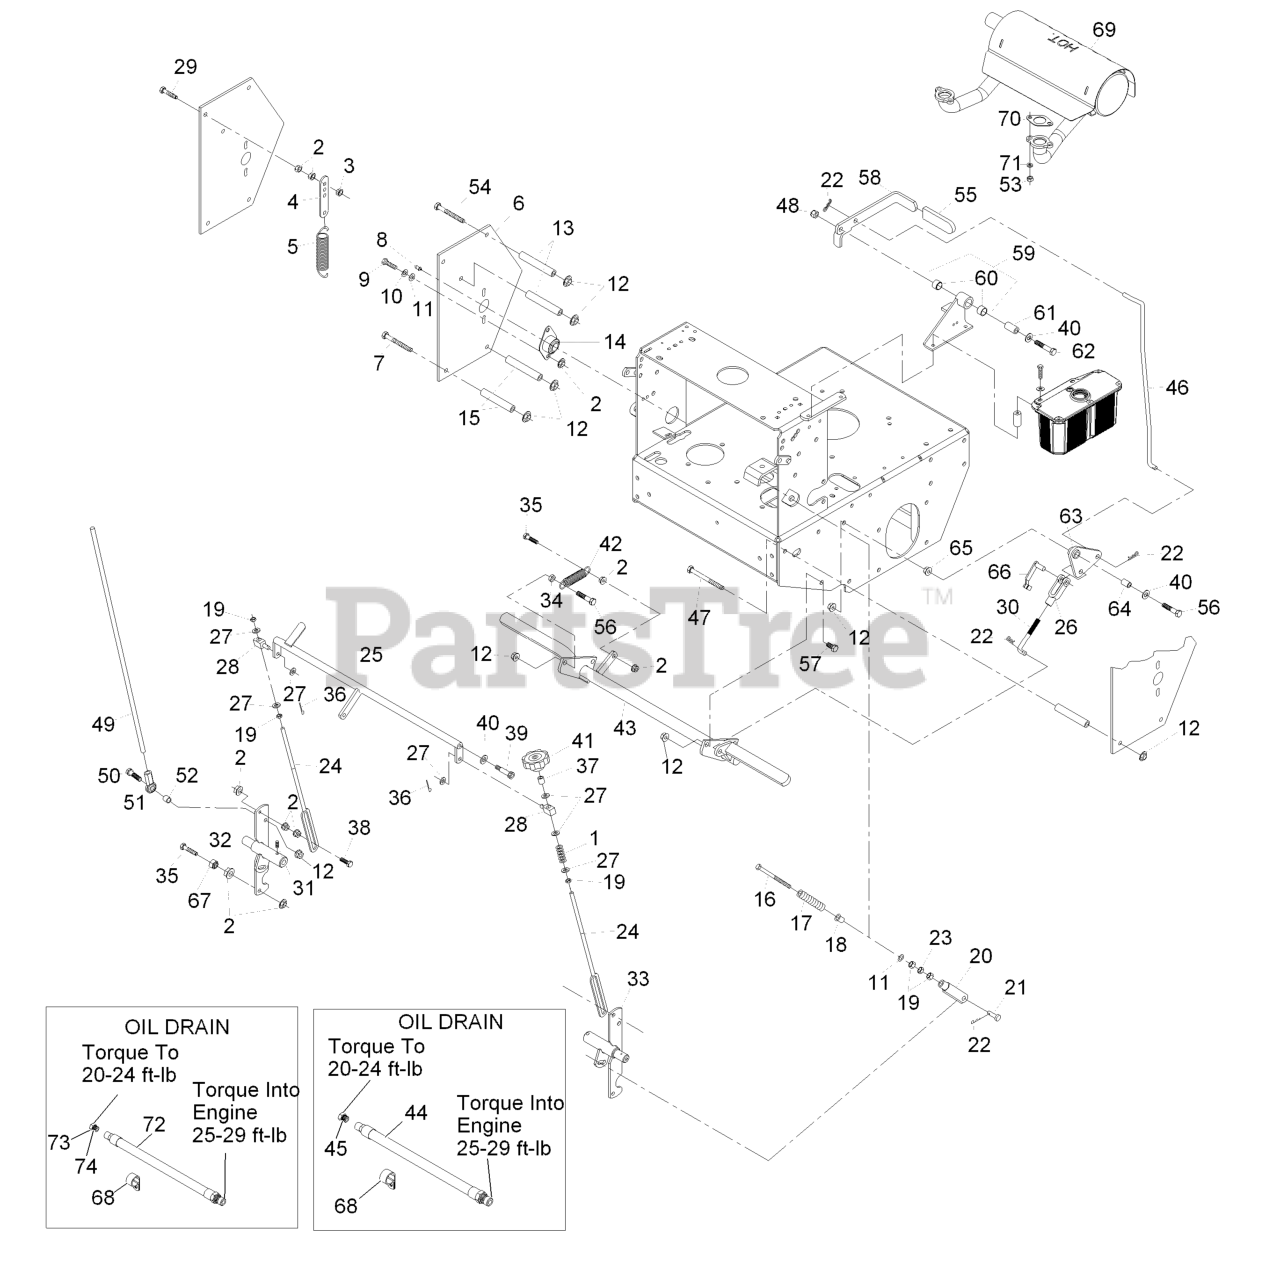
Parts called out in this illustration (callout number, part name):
1	SPRING-COMPRESSION
3	NUT-LOCK, NI
4	TAB-SPRING, EXTENSION
5	SPRING-EXTENSION
6	SHIELD-CONTROL
7	SCREW-HH
8	FITTING-GREASE
9	SCREW-HH
10	WASHER-LOCK
11	WASHER-FLAT
12	NUT-HHF, WHIZ
13	SPACER-SHIELD
14	BEARING-FLANGE, SIDE
15	SPACER-SHIELD
16	BOLT-RETURN, NEUTRAL
17	SPRING,COMPRESSION (NEUT)
18	BUSHING-FLANGED
19	NUT-HEX
20	YOKE-ADJUSTABLE
21	PIN-CLEVIS
22	PIN-COTTER
23	NUT-JAM
24	LINK-CONTROL, SPEED
25	CRANK-CONTROL, SPEED
26	YOKE-LINKAGE, BRAKE
27	WASHER-PLAIN
29	BOLT-TAP, HH
30	LINKAGE-LOWER
31	SCREW-SET
32	SHAFT-CONTROL, LH
33	SHAFT-CONTROL, RH
34	NUT-JAM
35	SCREW-HH, SPECIAL
36	PIN-COTTER
38	SCREW-HH
39	SCREW-HSH
40	WASHER-FLAT
41	KNOB-TRACKING
42	SPRING-IDLER
46	LINKAGE,UPPER- TTHP
47	SCREW-HH
48	NUT-LOCK, NI
49	LINK,DRIVE (PLTD)
50	SCREW-HH
51	JOINT-BALL END, LH
52	SPACER-TUBE, PUMP LINK
54	SCREW-HH
55	GRIP-LEVER
56	SCREW-HH
57	SCREW-HH
58	LEVER,PARK BRK W/DECAL
59	BRACKET ASM
60	SLEEVE-BUSHING
61	BUSHING-PIVOT
62	SCREW-HH
63	BELLCRANK ASM
64	BUSHING-PLASTIC
66	PIN-SPRING, CLEVIS
67	NUT-JAM
68	CLIP-LOOM
69	MUFFLER,HORIZONTAL
70	GASKET-EXHAUST
71	WASHER-LOCK
72	ASM, ENGINE OIL DRAIN HOS
73	PLUG-HH
74	O-RING
